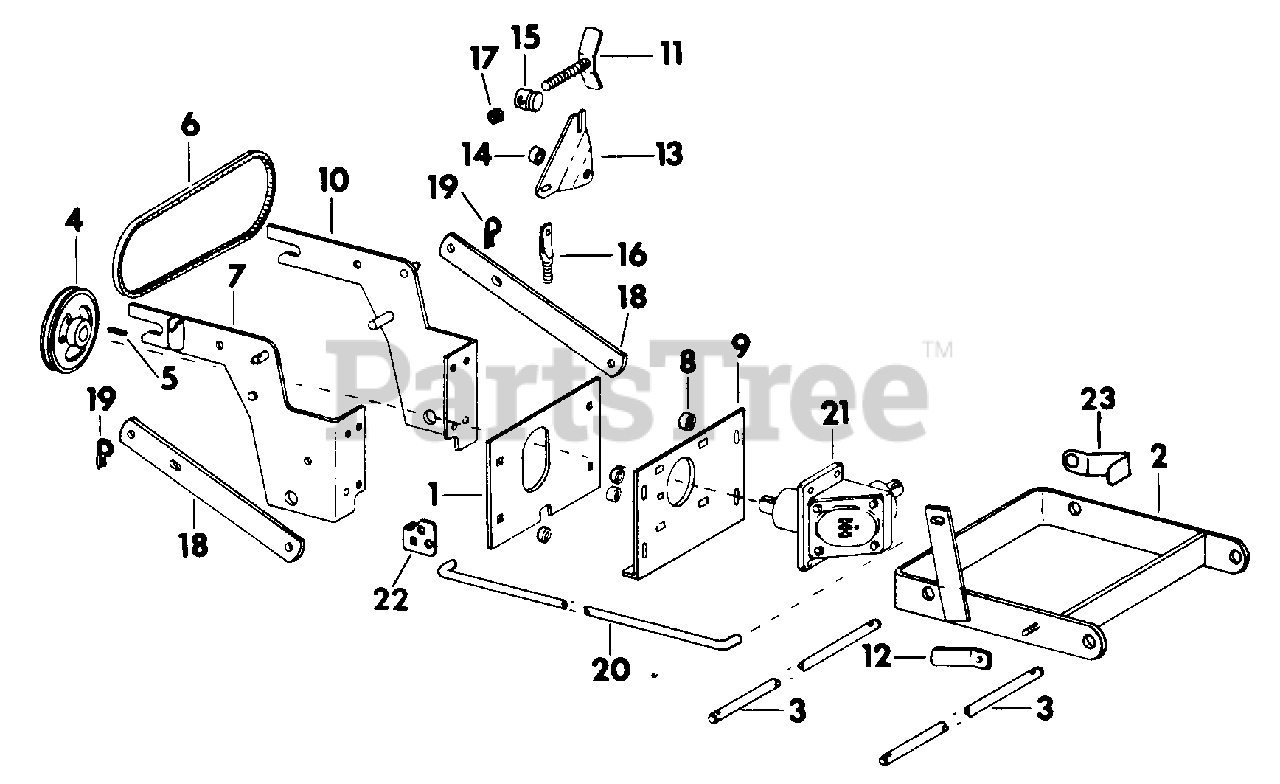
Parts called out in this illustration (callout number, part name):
1	Plate Assy, Front
2	Bracket, Lift
3	Shaft, Pivot
4	Pulley, w/Set Screws, Gear Box
5	Key, 3/16 X 1-1/4 Sq Parallel
6	Belt, Main Drive -For Cadet Tractors 700 thru 1650
7	Bracket, Front RH
9	Plate, Gear Box Mounting
10	Bracket, Front LH
11	Bolt, Belt Adjusting
12	Nut Assy, Wing
13	Plate, Pivot
17	Nut, 1/2-13 LH Slt Hex
19	Pin, Hair
21	Gear Box Assy
22	Bracket, Lift Handle -For Cadet Tractors 482 thru 782
